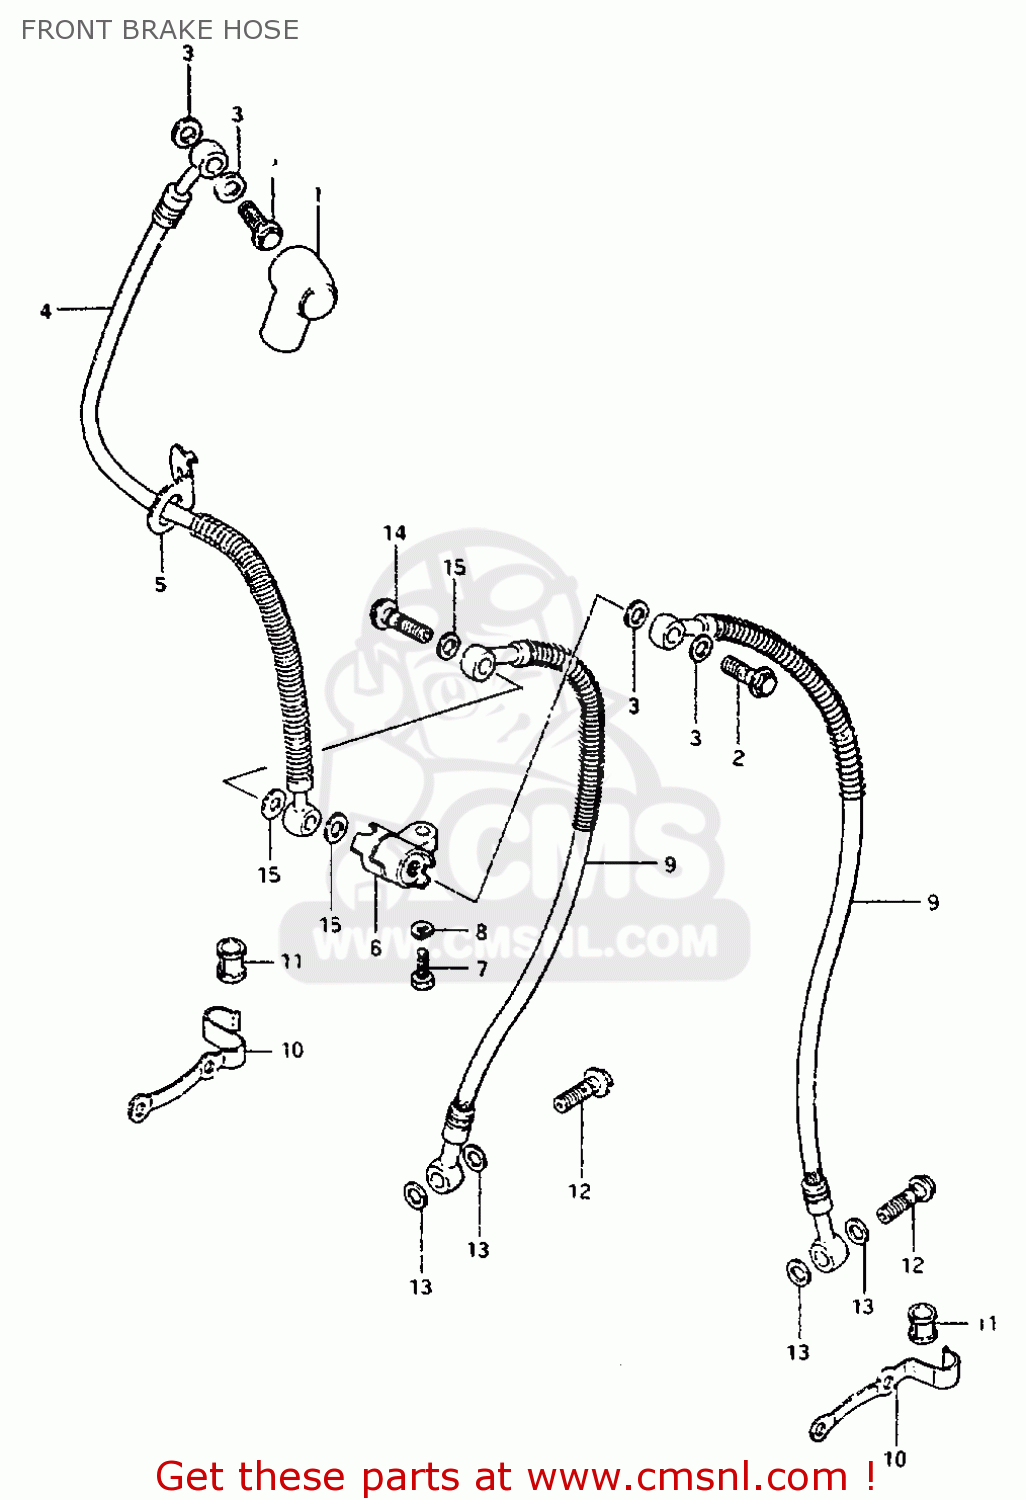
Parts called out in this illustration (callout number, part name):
1	BOOT,MASTER CYLINDER
2	BOLT,UNION
3	WASHER
4	HOSE,FRONT BRAKE NO.1
5	GUIDE,BRAKE HOSE
6	JOINT,BRAKE HOSE
7	BOLT
8	LOCK WASHER
9	HOSE,FR BRAKE NO.2,L
10	GUIDE,BRAKE HOSE NO.2
11	BUSH,BRAKE HOSE GUIDE,NO.2
12	BOLT,UNION
13	WASHER
14	BOLT,UNION
15	WASHER
